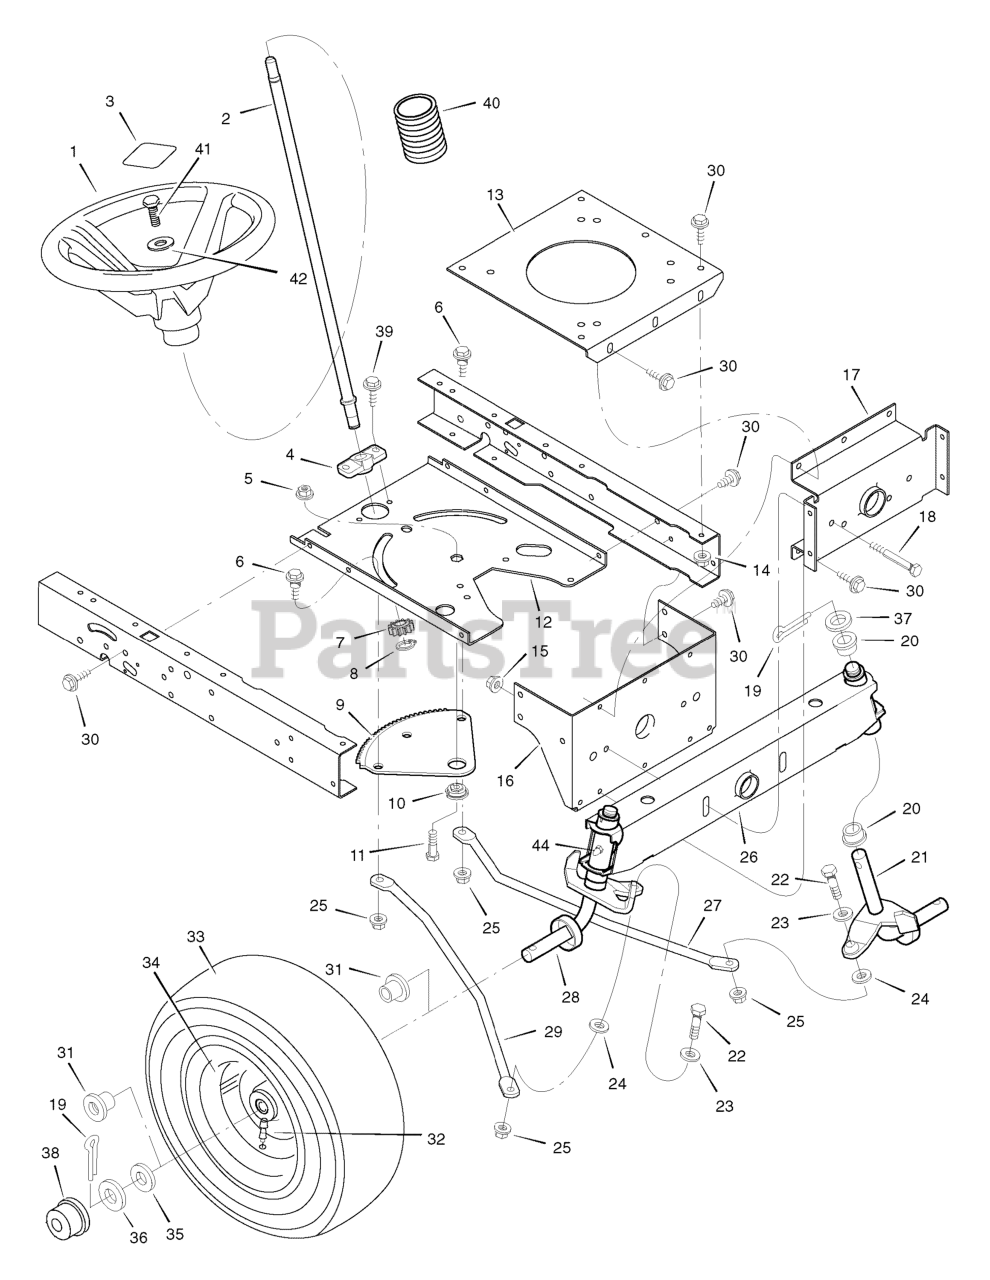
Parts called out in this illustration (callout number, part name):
1	Wheel, Steering
2	Post, Steering
3	Cover, Steering Wheel
4	Bearing
5	Nut, Flange **
6	Bolt, Shoulder
7	Gear, Pinion
8	Ring, Snap **
9	Gear, Sector
10	Bearing
11	CAPSCREW, Hex Head, 5/16-18 x 1
12	Plate, Steering
13	Plate, Engine
14	Nut, Flange
15	Nut, Flange
16	Bracket, Hanger
17	Axle, Hanger
19	Pin, Cotter
20	Bearing
21	Spindle Assembly, Left
22	Bolt
23	Washer
24	Washer
25	Nut, Flange
26	Axle Assembly
27	Drag Link, Left
28	Spindle Assembly, Right
29	Drag Link, Right
31	Bearing, Wheel
32	Stem, Valve
33	Tire *
34	Wheel andTire Assembly
38	Hub Cap
40	Bellows
41	Screw, Hex
42	Washer
44	Fitting, Grease
